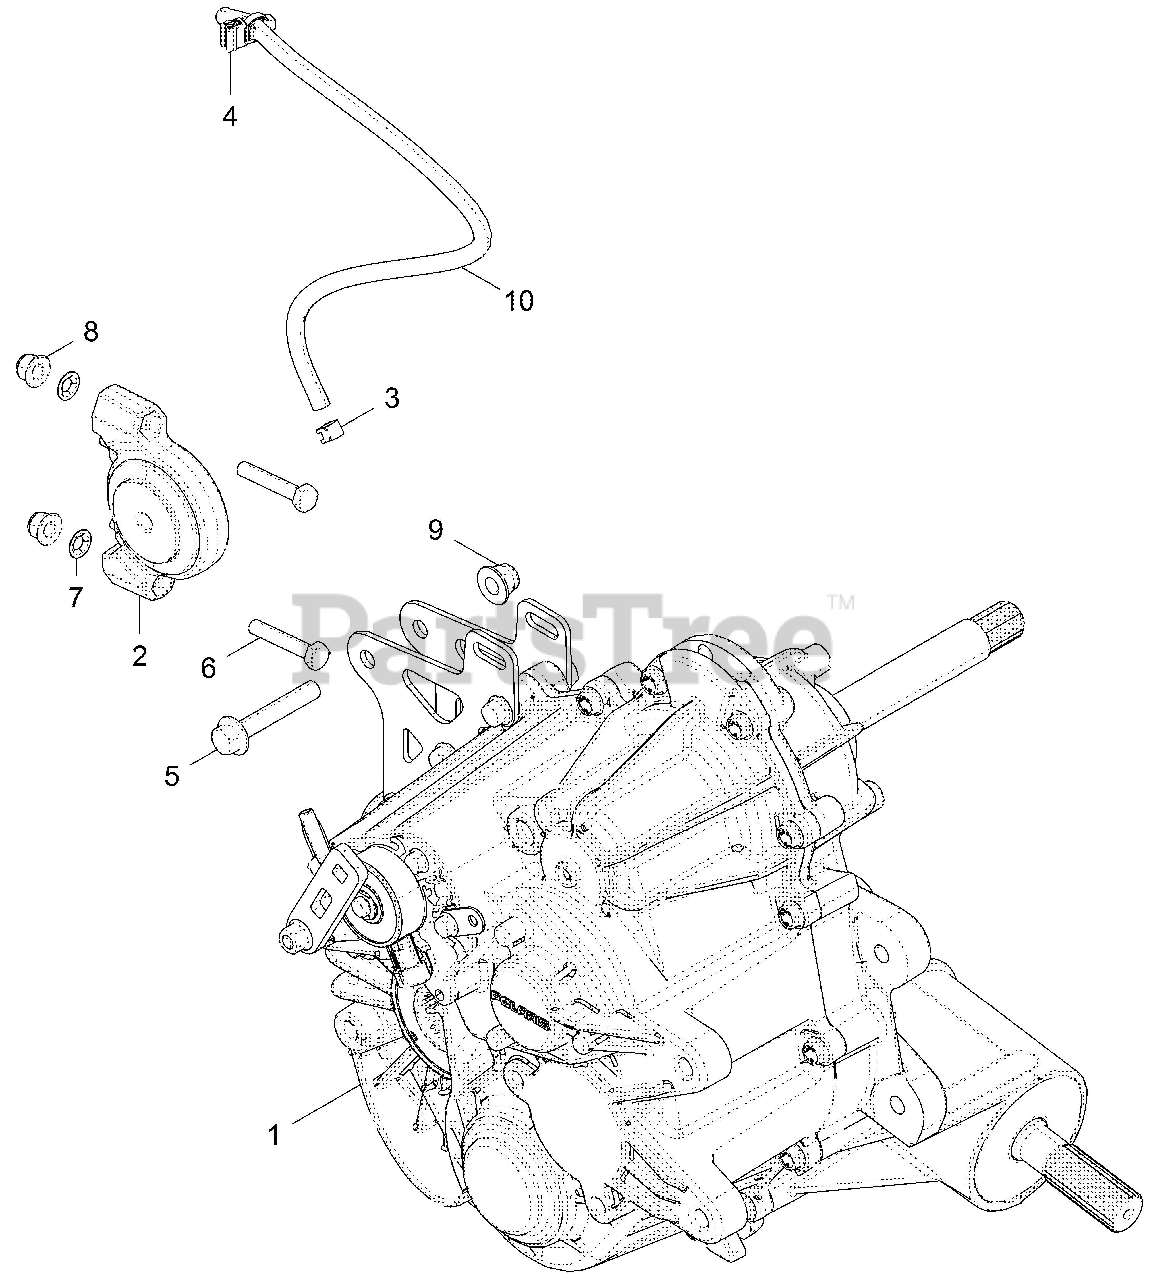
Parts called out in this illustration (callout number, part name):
1	#N/A
2	MOUNT-ISOLATOR,DRIVELINE
3	CLAMP-HOSE, 17/32, GREEN
4	CLIP-ROUTING
5	BOLT-M10X1.25X60,HXFLG-OLIVE D
6	SCR-HH M8X1.25X45 8.8 ZOD
8	NUT-M8X1.25,FLG,NYLOC-OLIVE D
9	NUT-M10X1.25,FLG,NYLOC-OLIVE D
10	FUEL LINE-50 CM
